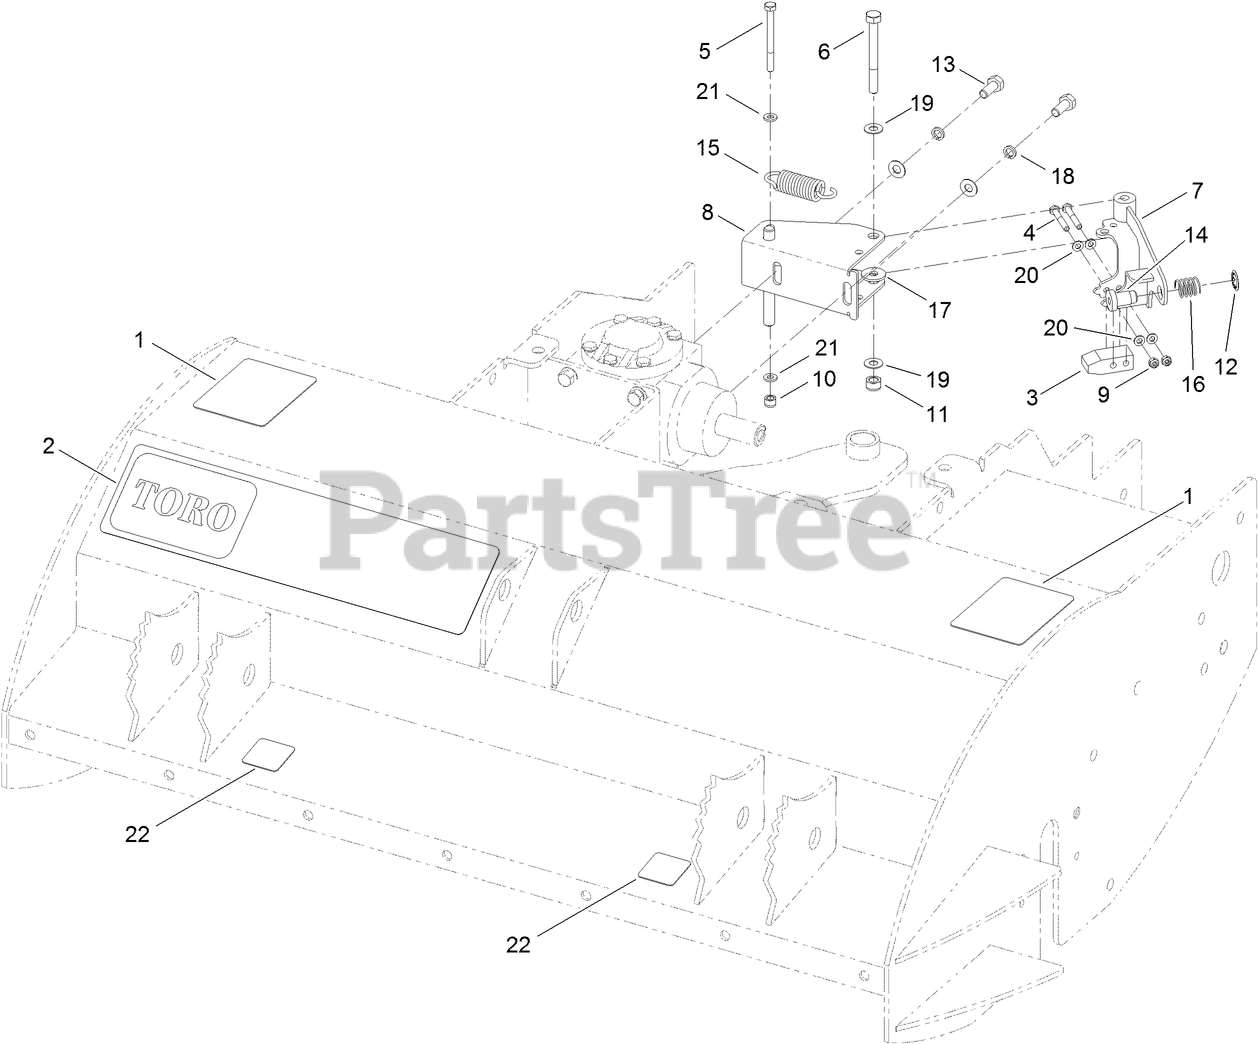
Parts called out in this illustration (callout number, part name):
1	DECAL-DANGER, CE
3	BLOCK-BRAKE
5	BOLT-HH
7	BRAKE-ARM
8	BRACKET-MOUNT, BRAKE
9	NUT-NYLOC
10	NUT-NYLOC
11	NUT-HEX, NI
12	RING-PUSH ON
13	SCREW-HH
14	SPACER-FLANGED
15	SPRING-TENSION
16	SPRING-COMPRESSION
17	WASHER
18	WASHER-SPRING
19	WASHER
20	WASHER
21	WASHER-PLAIN
22	DECAL-HOC
